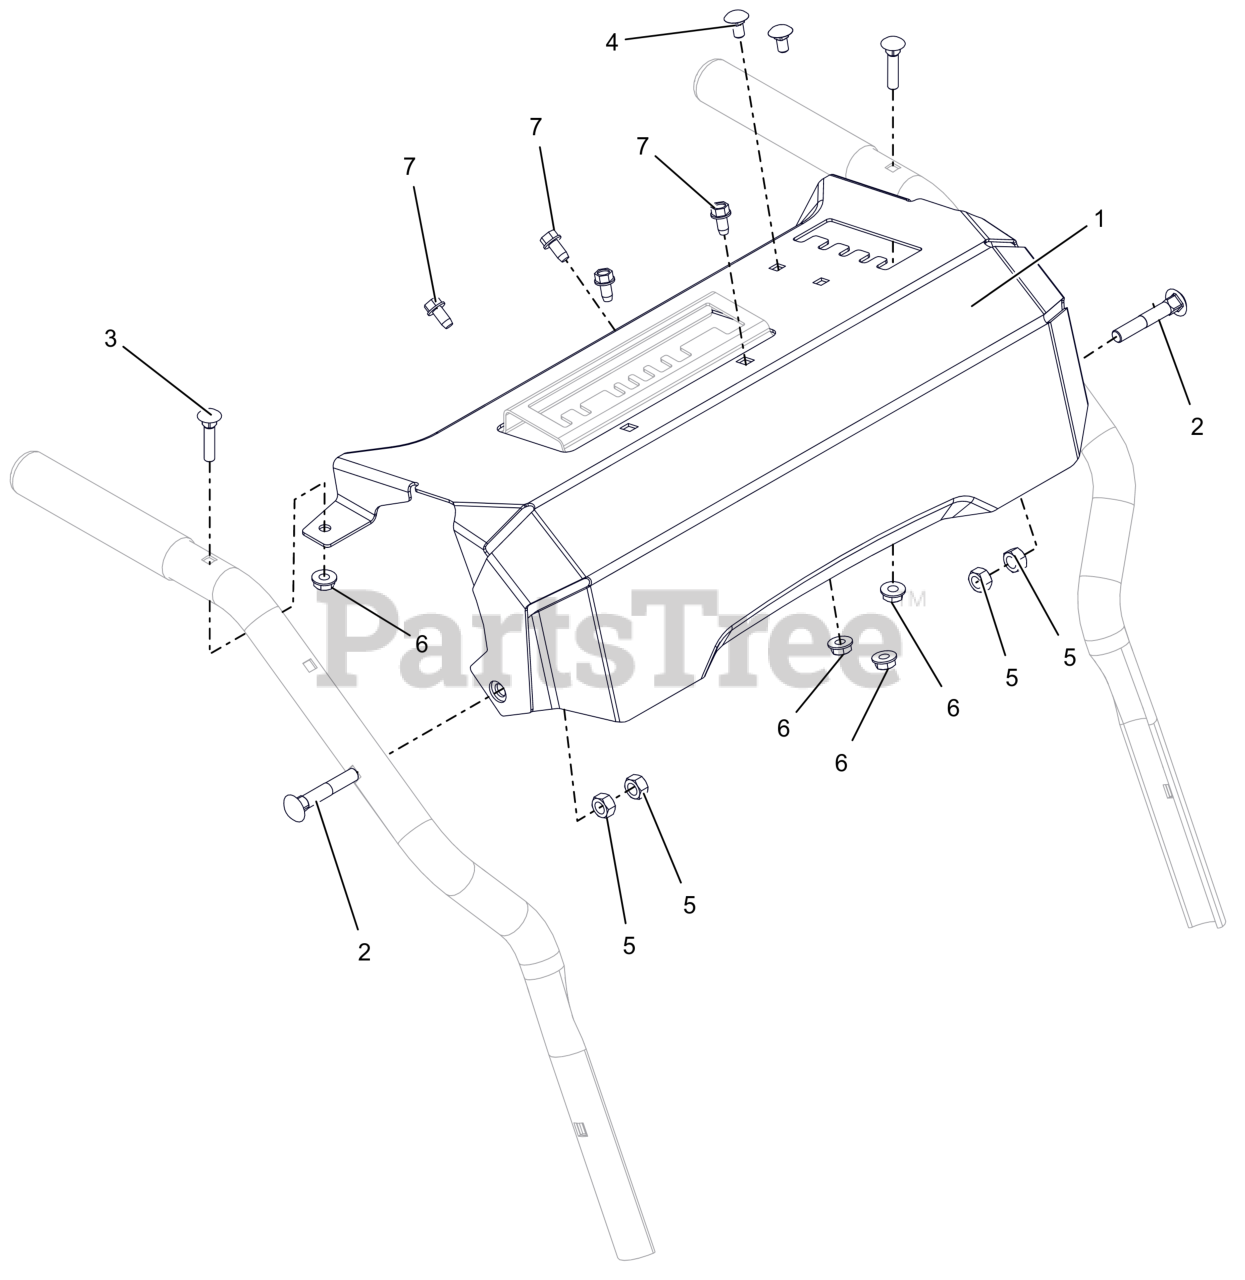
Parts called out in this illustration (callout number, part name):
1	CTRL PANEL W/DECAL-SNOTEK REMO
2	BLT-RDHDXLSQNK .31-18X2.0 G5YZ
3	BLT-RDHDXLSQNK.25-20X1.25 G5ZC
4	BLT, RHSN .25-20X.500 G5 ZCC
5	NUT,LK-CTR .31-18 GA ZCC
6	NUT-LK-TOP-FLG .250-20 GF ZCC
7	SCR-TAP .25-20X.50 HWH ZCC
